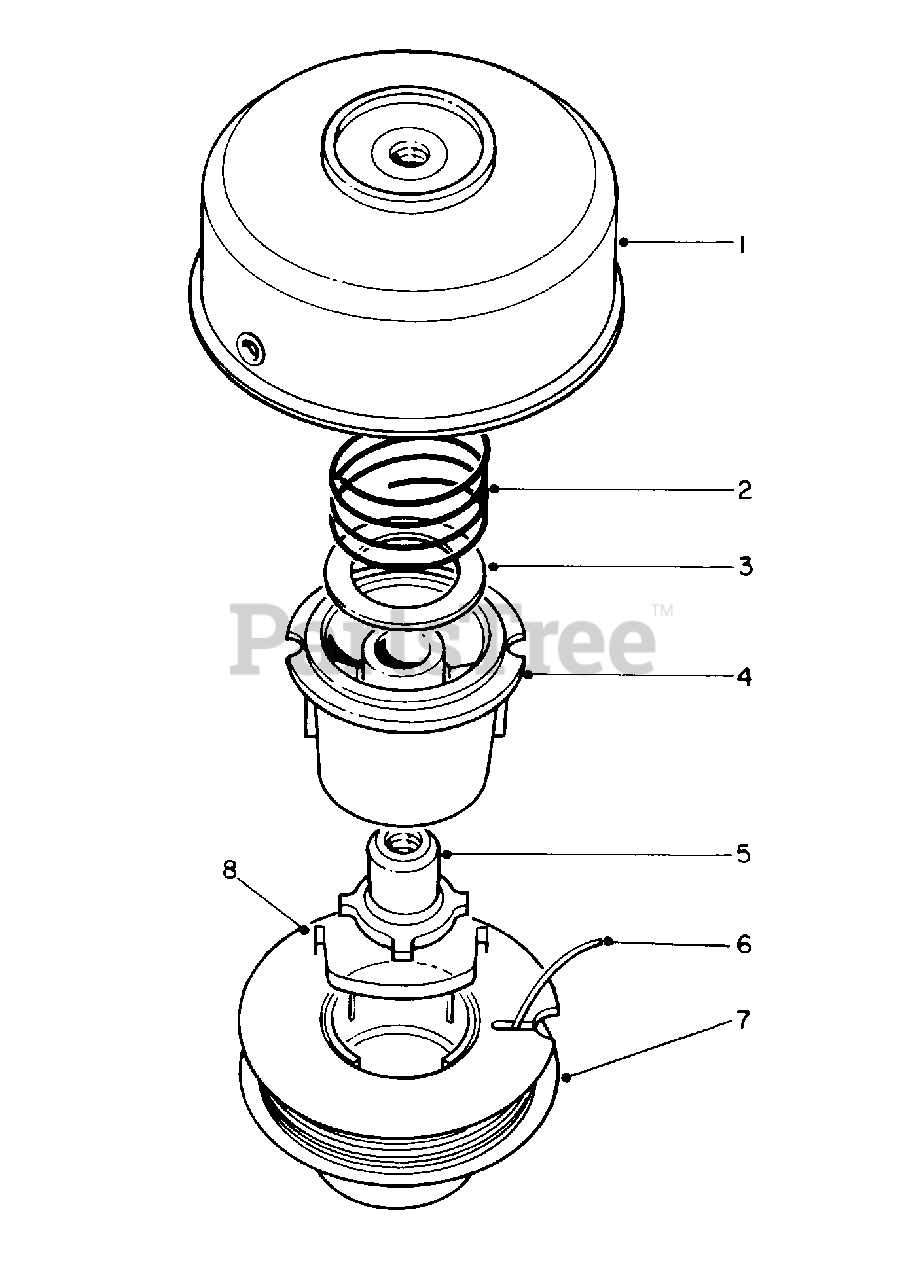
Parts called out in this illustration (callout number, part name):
1	Drum/Eyelet
4	Core-Spool
5	Driver L.H.
6	Line Cutting .095 Dia.
7	Spool Prewound .095 Dia. 30' (Incl. Ref. #8)
8	Saddle-Spool Cap
